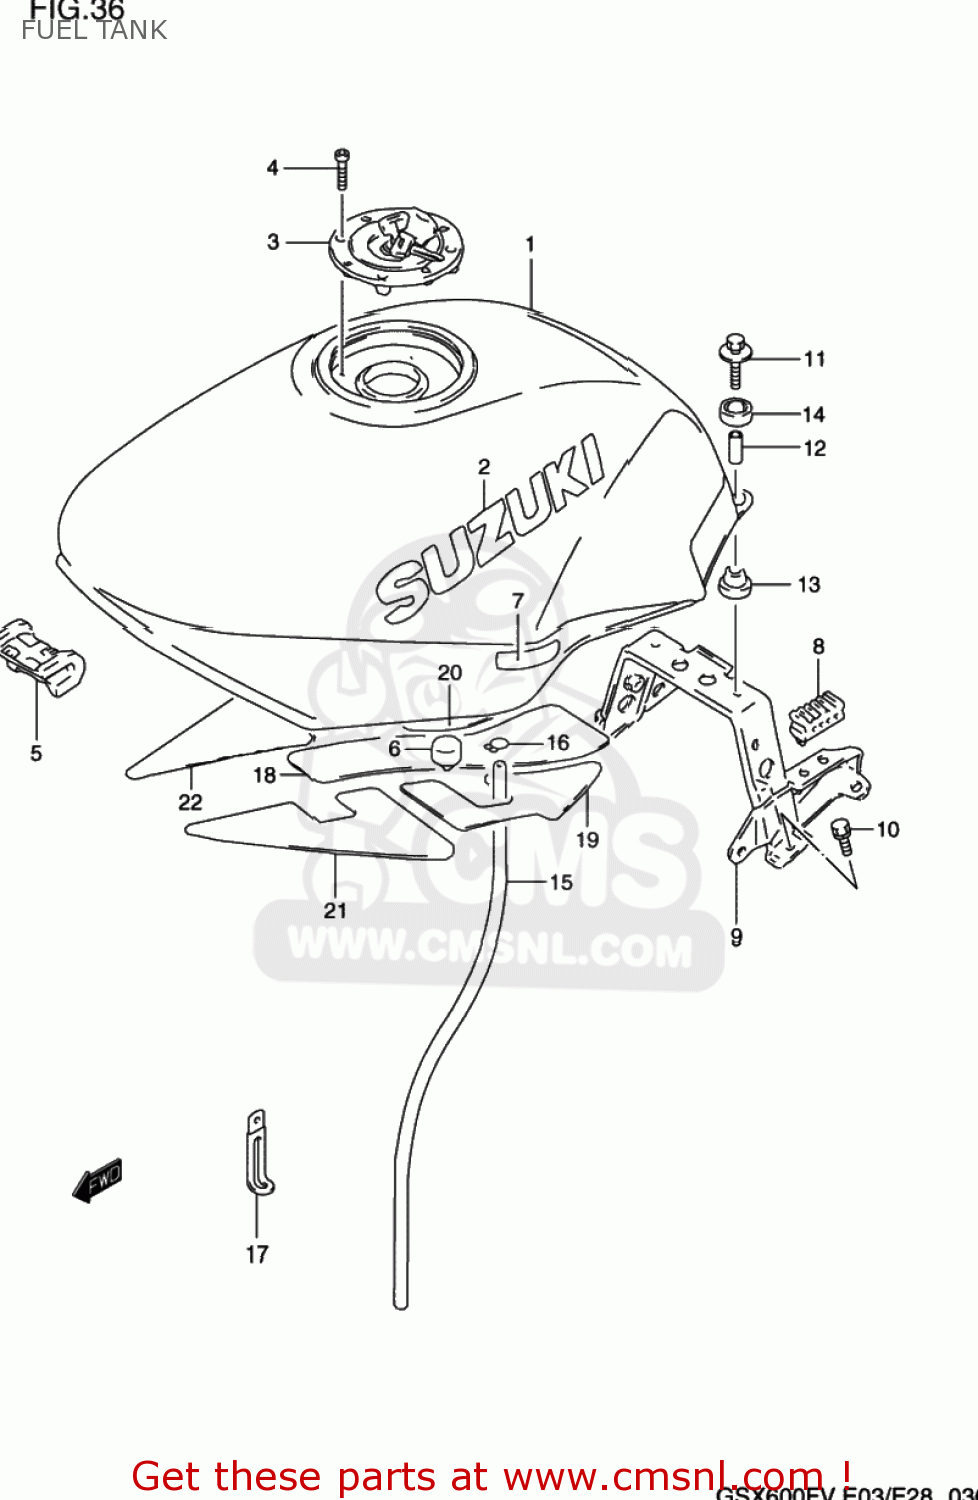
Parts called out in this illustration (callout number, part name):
1	TANK ASSEMBLY,FUEL
2	EMBLEM,FUEL TANK
3	CAP SET,FUEL
4	BOLT(5X20)
5	CUSHION,FUEL TANK FR
6	CUSHION
7	PROTECTOR(12X40)
8	CUSHION,SEAT(40X20X15)
9	BRACKET,FUEL TANK RR
10	SCREW
11	BOLT(6X30)
12	SPACER(6.5X9X18)
13	CUSHION
14	CUSHION
15	HOSE,FUEL TANK WATER DRAIN
16	CLIP
17	CLAMP(L:120 T:1.0)
18	HEATSHIELD,CTR
19	HEATSHIELD,RR,L
20	HEATSHIELD,RR,R
21	HEATSHIELD,FR,L
22	HEATSHIELD,FR,R
